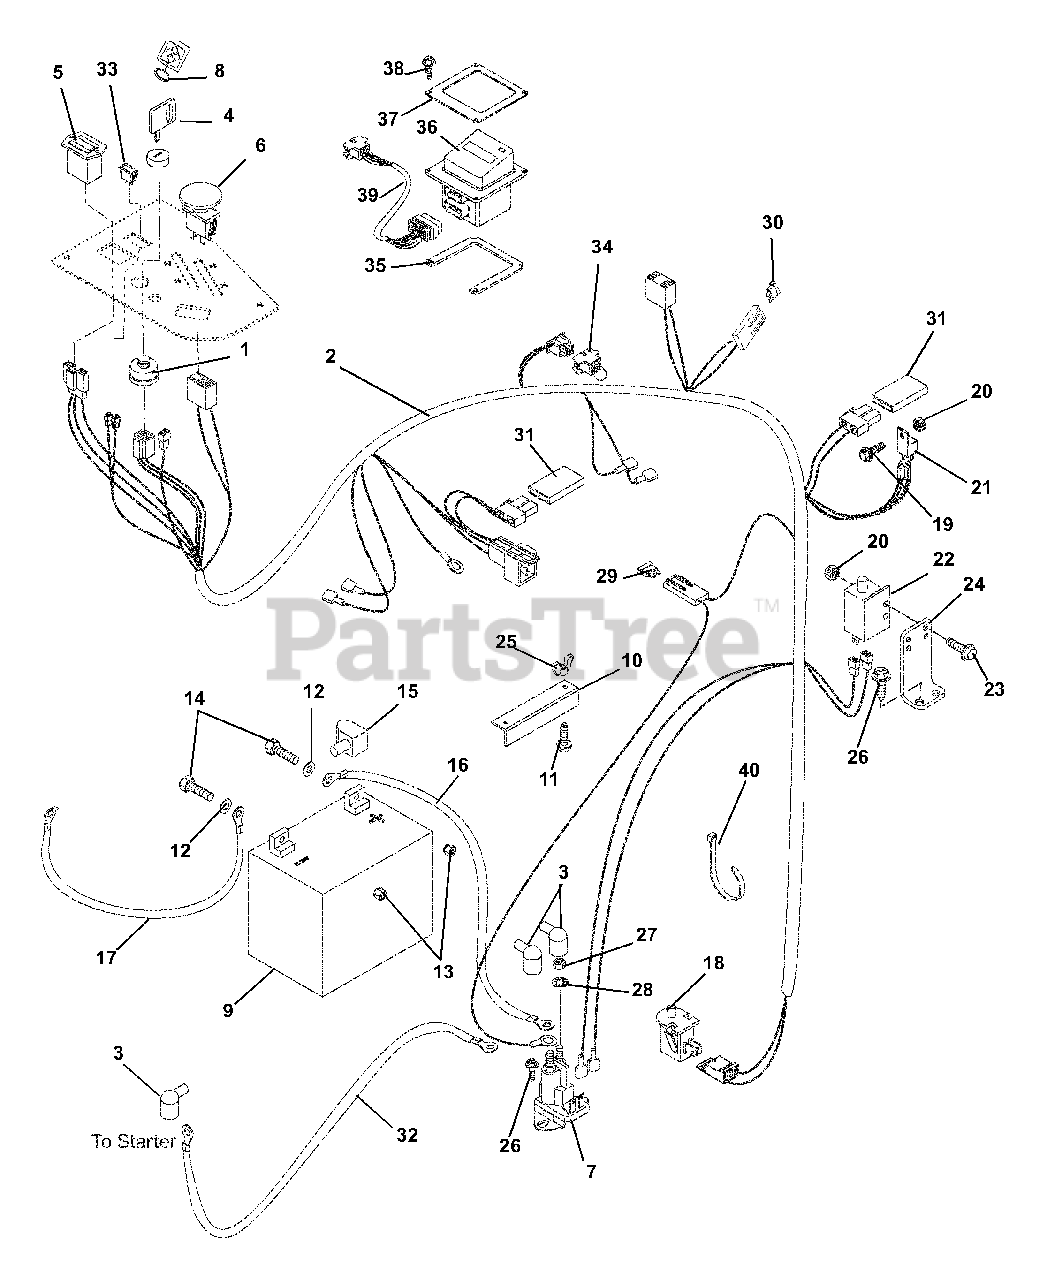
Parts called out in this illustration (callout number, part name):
1	Key Switch
2	Harness, Z 6-Pin Wiring
3	Boot, Eyelet Terminal
4	Key with Shield
5	Hour Meter
6	Switch, Clutch With Retainer Ring
7	Solenoid
8	Key Chain
10	Hold Down
11	Bolt, Round Head Square Neck .25-20 x 7.50
12	Washer, Flat Steel .281 x .620 x .065
13	Nut, Locking Top Flange .25-20
14	Bolt, Hex .25-20 x .75 Grade 5
15	Insulator
16	Cable, Positive Battery 9.00"
17	Ground Cable
18	Switch, Snap Mounting (N.O.)
19	Screw, Machine 10-24 x .50 Hex Washer Head
20	Nut, Locking Nylon 10-24 With Insert
21	Relay
22	Switch, Single Pole
23	Screw, Machine 10-24 x .75 Hex Washer Head
24	Mount, Brake Switch
25	Nut, Locking Wing .25-20
26	Screw, Tapping .25-20 x .50 Hex Washer Head
27	Nut, Jam .31-24
28	Washer, Locking .31 x .078 Regular
29	Fuse, 25 Amp
30	Fuse, 20 Amp
31	Diode, Connector Shell
32	Cable, Starter
33	Light, Indicator
34	Harness, Jumper (EYE-Q) (064)
35	Spacer, Enclosure Mounting (Bottom) (083)
36	Assembly, Eye-Q (083)
37	Plate, Eye-Q Stiffener (Top) (083)
38	Screw, Machine 10-24 x 1.0 Slotted Pan Black (083)
39	Harness, Eye-Q (083)
40	Cable Tie
